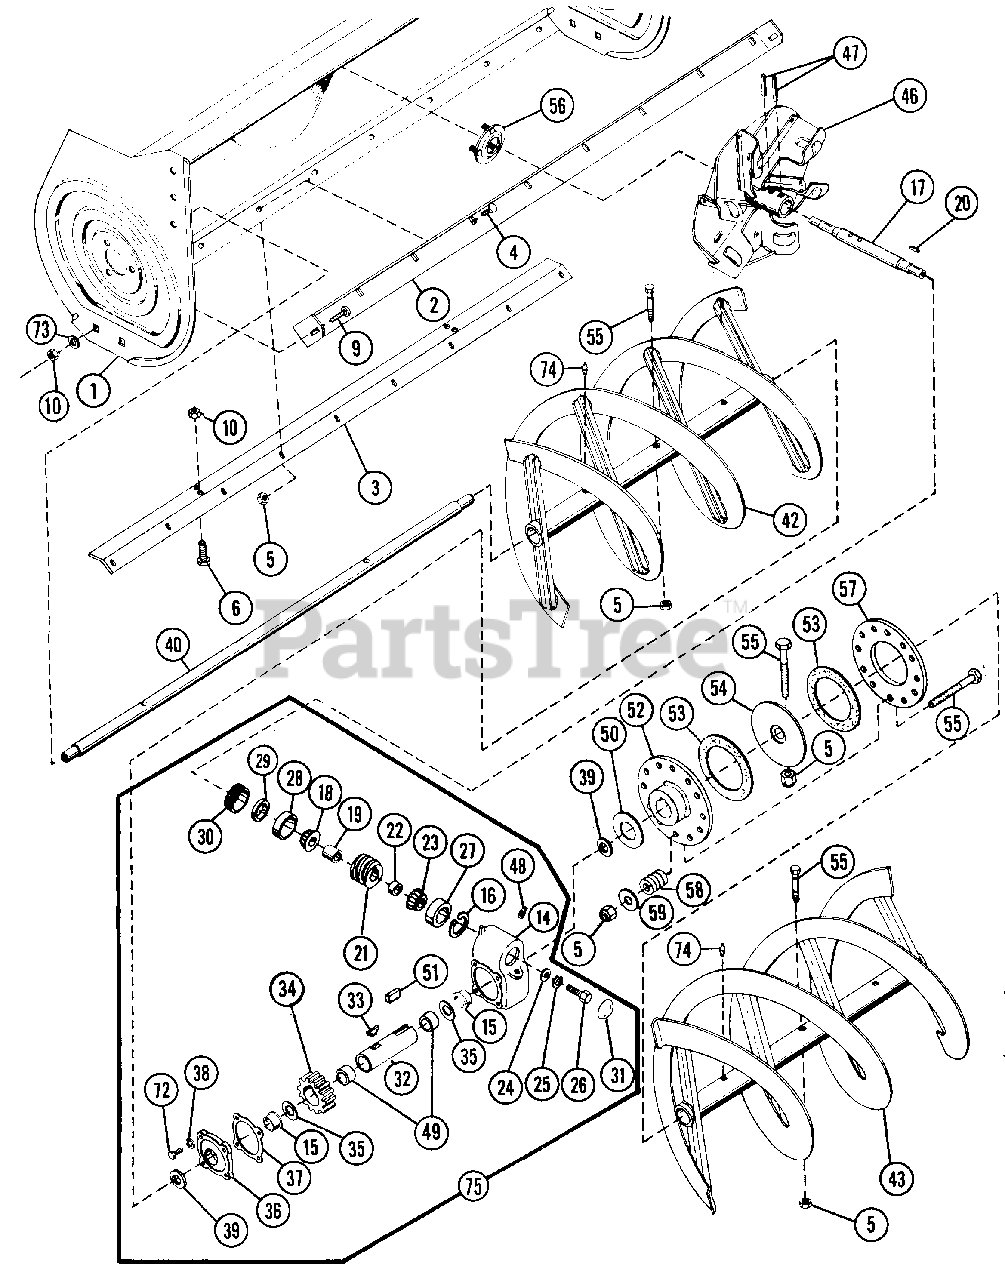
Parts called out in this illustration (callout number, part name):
1	40" SNO THRO HOUSING
1	48" SNO THRO HOUSING
2	SCRAPER BLADE - 40"
2	SCRAPER BLADE - 48"
3	SCRAPER BLADE BRACE - 40"
3	SCRAPER BLADE BRACE - 48"
4	BOLT, CARRIAGE 5/16-18X.75
5	NUT, LOCK 5/16-18
6	BOLT, HEX 3/8-16X.75
9	BOLT, 3/8-16X1 RD HD SQ NK
10	NUT, LOCK 3/8-16
14	GEAR CASE
15	BUSHING, FLANGE 1.62X1.87X11
16	RING, SNAP INTERNAL 1.781
17	WORM SHAFT
18	BEARING CONE
19	BEARING SPACER
20	KEY, STRAIGHT SAE 1035
21	WORM
22	SPACER, BEARING
23	BEARING CONE
24	WASHER, FLAT .344X.688X.065
25	WASHER, LOCK 3/8 SP HEAVY
26	BOLT, HEX 5/16-18X.75
27	BEARING CUP
28	BEARING CUP
29	SEAL
30	ADJUSTMENT PLUG
31	CAP, DUST
32	GEARCASE SHAFT
33	KEY, FEATHER
34	GEAR, WORM
35	WASHER, 1.625X2.50X.012
36	COVER, GEAR CASE
37	GASKET
38	WASHER, LOCK 1/4 EXT TH TYA
39	SEAL
40	40" RAKE SHAFT
42	RIGHT RAKE - 40"
43	LEFT RAKE - 40"
46	FAN
47	PIN, ROLL 5/16X1.75
48	PIPE PLUG
49	BUSHING, SLEEVE
50	WASHER
51	KEY, STRAIGHT
52	DRIVER
53	FRICTION DISC
54	DRIVER PLATE
55	BOLT, HEX 5/16-18X2.00
56	BEARING, FLANGE
57	PRESSURE PLATE
58	SPRING, COMPRESSION
59	WASHER, FLAT
72	BOLT, HEX 1/4-20X.875
73	WASHER, FLAT .406X.812X.065
74	SPIN DRIVE ZERK FITTING
75	GEARCASE ASSEMBLY
